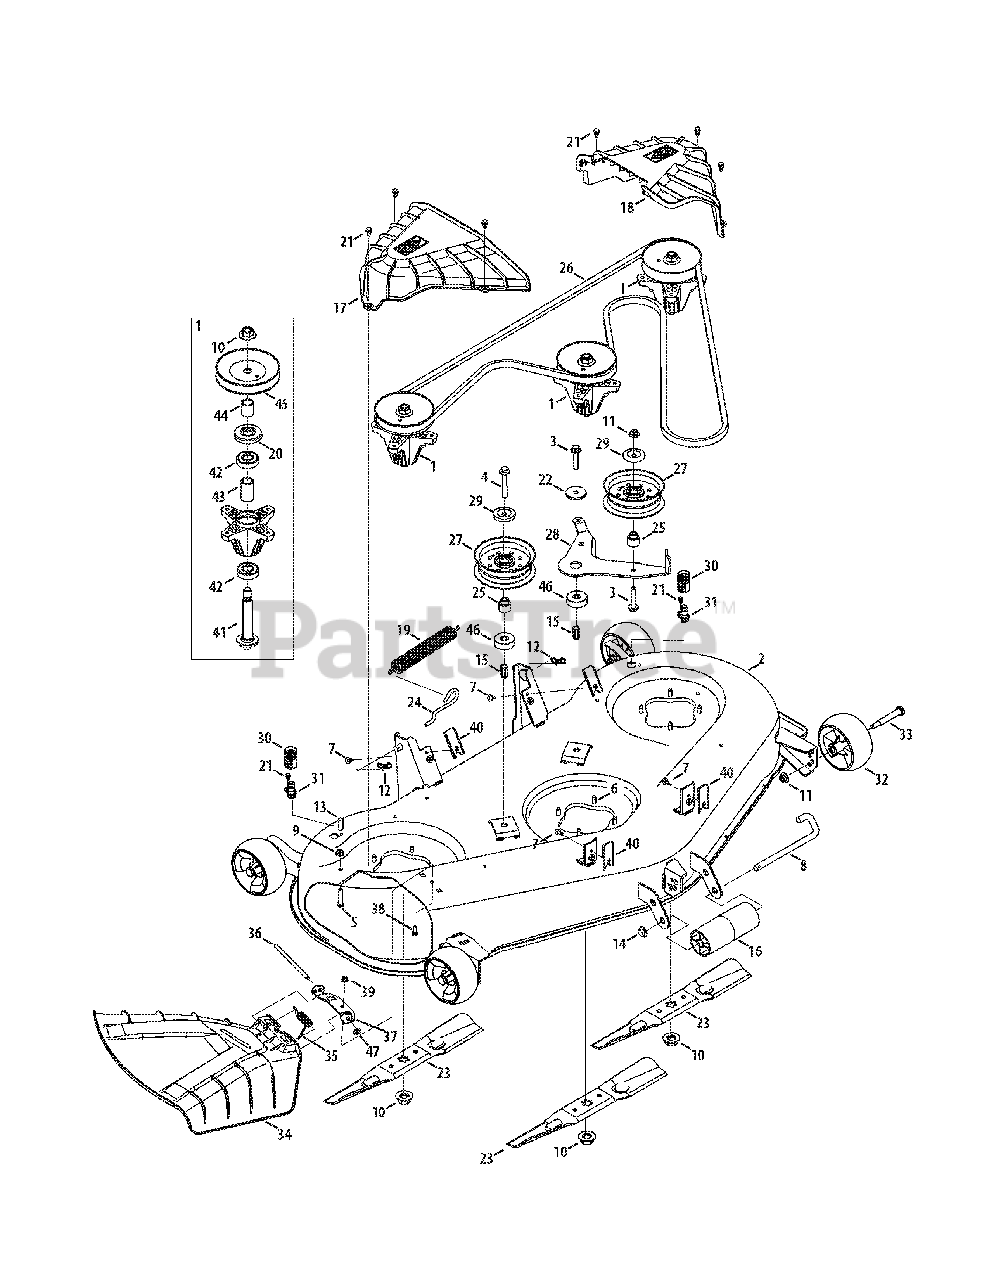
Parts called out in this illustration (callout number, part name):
1	Spindle Ass’y, Pulley, 5.37 Dia
2	Deck Assembly, 50"
3	Hex Cap Screw, 3/8-16 x 2.00
4	Hex Cap Screw, 3/8-16 x 2.75
5	Hex Cap Screw, 5/16-18 x 1.50
6	Screw, Self-tapping, 5/16-18, 0.750,
7	Screw, M6-1 x .625
8	Roller Pin, 1/2 x 7.31 Lg
9	Nut, Flange Lock, 5/16-18, Nylon
10	Nut, Flange, 5/8-18
11	Flange Lock Nut, 3/8-16
12	Bow-Tie Cotter Pin
13	Vinyl Cap, .29 x 1.00
14	Push Cap, 1/2"
15	Rivet Nut, 3/8-16
16	Front Roller
17	Belt Cover, RH
18	Belt Cover, LH
19	Spring, Extension, 1.25 OD x 8.5
20	Bearing Shield
21	Shoulder Screw, 1/4-20 x 0.50
22	Shoulder Spacer, .970 x .190
23	Blade, Cut, 17.27" 2-In-1, Cub
24	Deck Spring Rod
25	Shoulder Spacer
26	Belt, V-Type, B Sec x 134
27	Pulley, Idler, 4.50" Dia.
29	Pulley Cap
30	Coupler, Water
31	Deck Wash Nozzle
32	Wheel, Deck, 5.0 Dia. Ball
33	Bolt, Shoulder, .496 x 2.50, 3/8-16
34	Chute Deflector Assembly
35	Spring, Torsion, .440 ID x 1.75
36	Hinge Pin
38	Hex Cap Screw, 1/4-20 x .62
39	Nut, Flange Lock, 1/4-20, Nylon
40	Bracket, Lift, Stop
41	Shaft, Spindle, 6.11
42	Bearing, Ball, .787id x 1.85 Od x .551
43	Spacer, .792 x 1.060 x 1.860
44	Spacer, .792 x 1.060 x 1.782
45	Pulley, Deck, 5.00 Dia.
46	Spacer, .385 ID x 1.75 OD x .585
47	Push Cap
